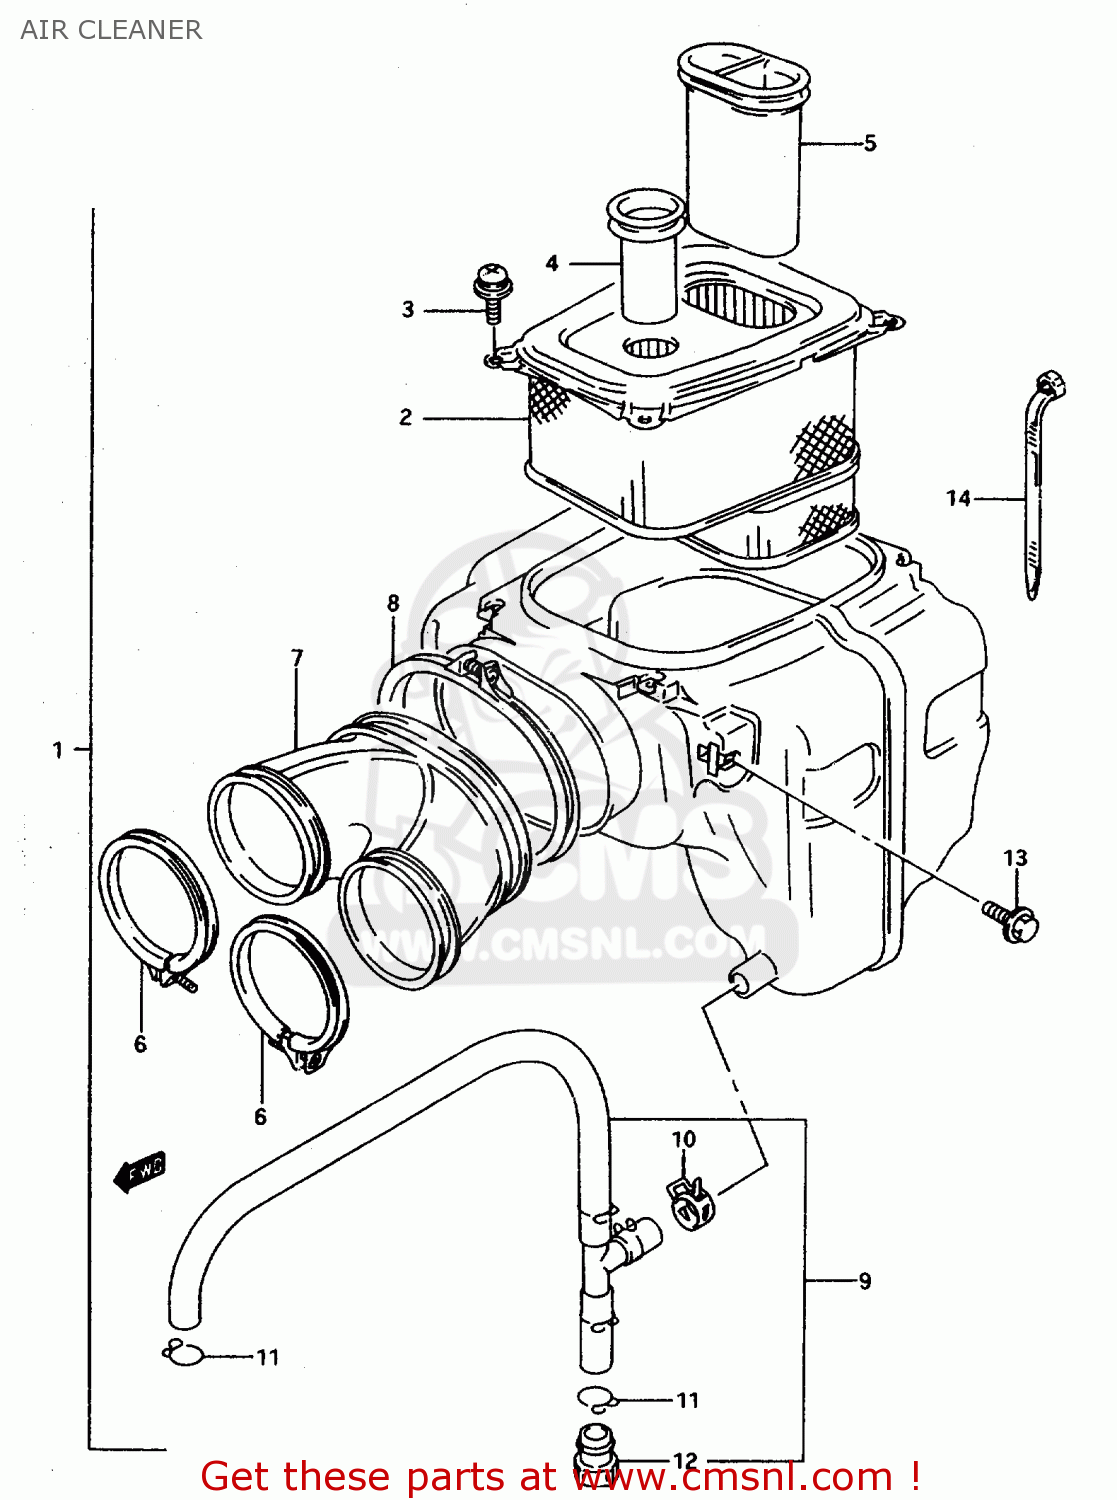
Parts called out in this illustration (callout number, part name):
1	CLEANER ASSY, AIR
2	FILTER ASSY
3	SCREW
4	TUBE,INLET NO.2
5	TUBE,INLET NO.1
6	CLAMP
7	TUBE,AIR CLEANER OUTLET
8	CLAMP
9	TUBE, BREATHER
10	CLIP
11	CLIP
12	PLUG
13	BOLT(6X16)
14	CLAMP L:165
